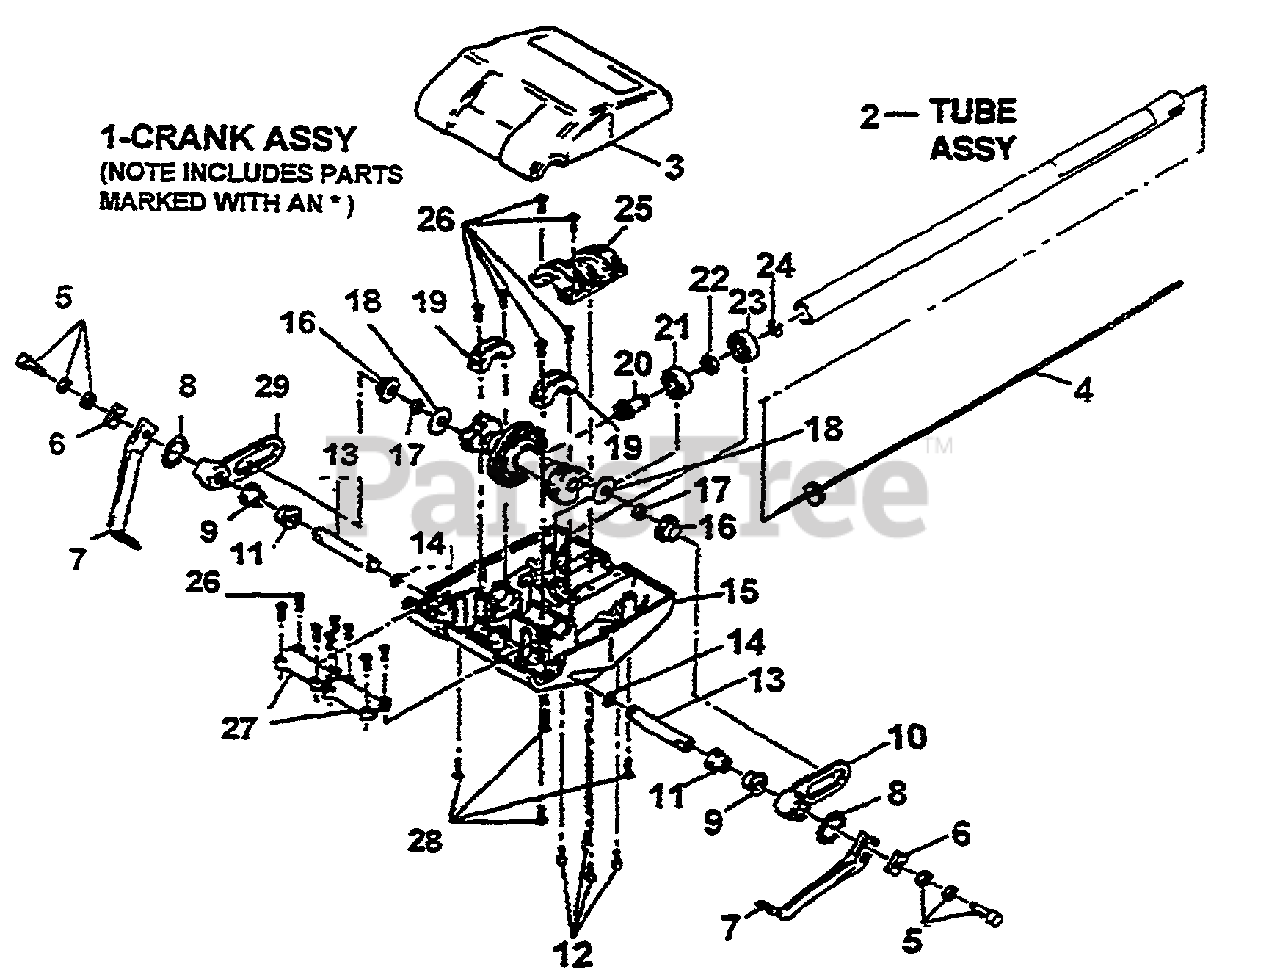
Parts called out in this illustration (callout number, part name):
1	CRANK ASSY
2	TUBE ASSY
3	UPPER COVER
4	FLEX CABLE
5	BOLT, SEMS
6	TINE SUPPORT
8	"O" RING
10	ROCKER ARM L.H.
12	SCREW
13	ROCKER SHAFT
14	WIRE RING
15	LOWER COVER
16	BEARING CAP
17	NEEDLE BEARING
18	WASHER
19	CRANKSHAFT CLAMP
20	PINION GEAR
21	BEARING
24	SNAP RING
25	SHAFT CLAMP
26	SCREW
27	SHAFT CLAMP
29	ROCKER ARM R.H.
